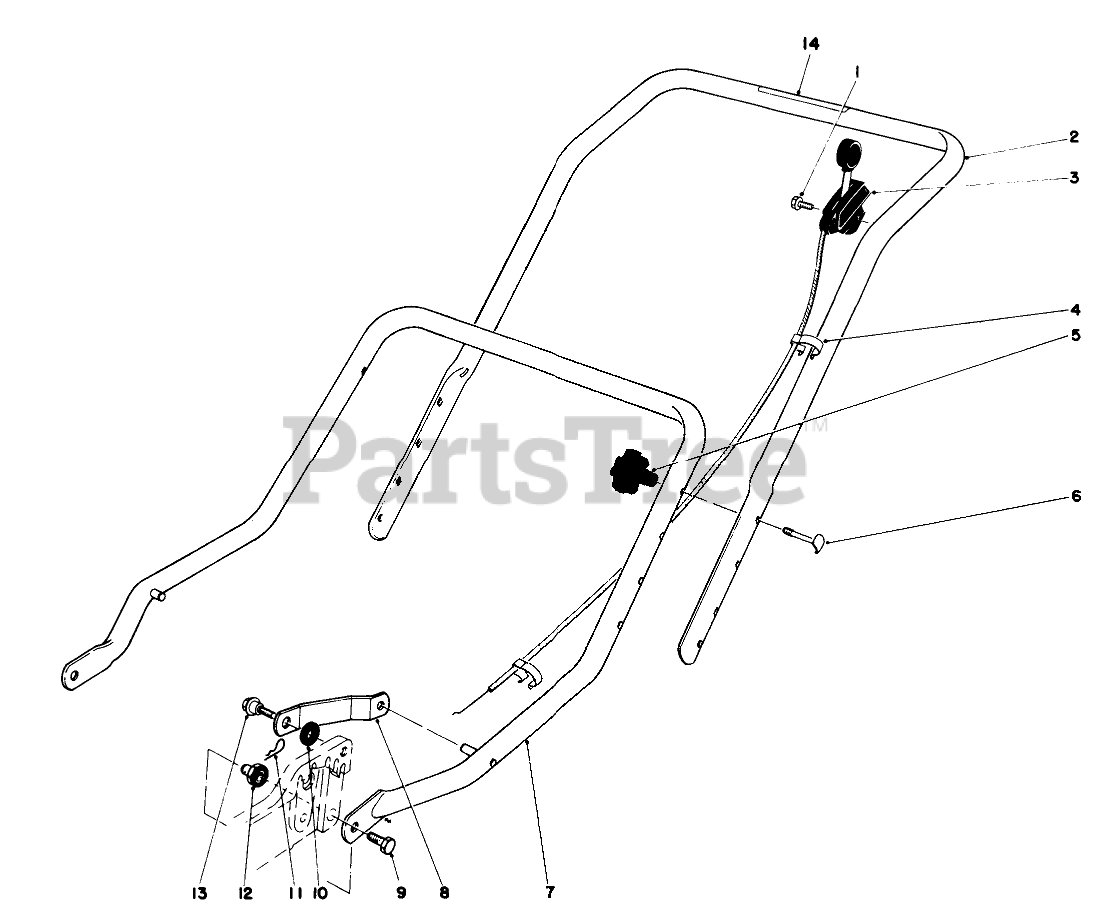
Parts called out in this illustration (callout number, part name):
2	Upper Handle
3	Throttle Control
4	BOWDEN CLIP
6	HANDLE SCREW
7	Lower Handle
8	HANDLE LATCH
9	SCREW-HH
10	SPACER
11	PIN-COTTER, HAIR
12	HANDLE PIVOT NUT
13	SCREW-SHOULDER
14	Decal
